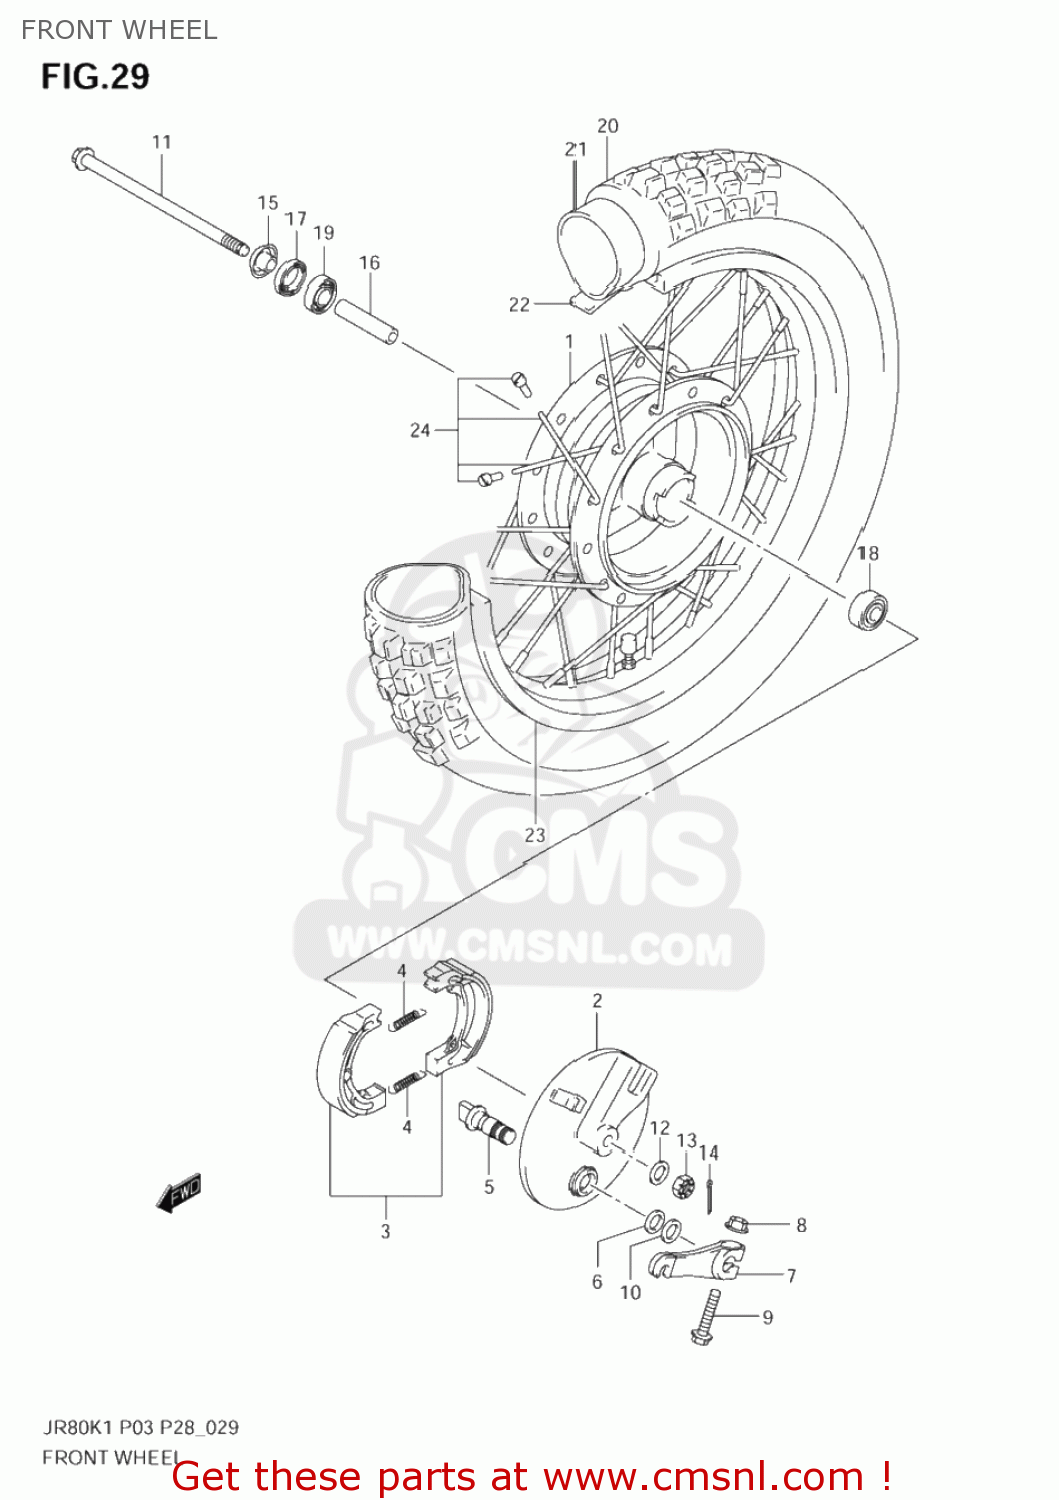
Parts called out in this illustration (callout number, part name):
1	HUB,FR
2	PANEL,FR BRAKE ANCHOR
3	SHOE SET,BRAKE (NAS)
4	SPRING(L:35.8)
5	CAM,FR BRAKE
6	O RING(D:2.5,ID:13.8)
7	LEVER,FR BRAKE CAM
8	NUT
9	BOLT
10	WASHER(14.5X22X1.6)
11	AXLE,FR
12	WASHER(10.5X20X2.3)
13	NUT
14	PIN 20X20
15	SPACER,FR AXLE,R
16	SPACER(10.1X16X51)
17	SEAL,OIL(15X31X5)
18	BEARING
19	BEARING
20	TIRE(2.25 14)
21	TUBE,INNER
22	PROTECTOR,INNER TUBE
23	RIM,FR WHEEL(1.40X14)
24	SPOKE SET,FR WHEEL
